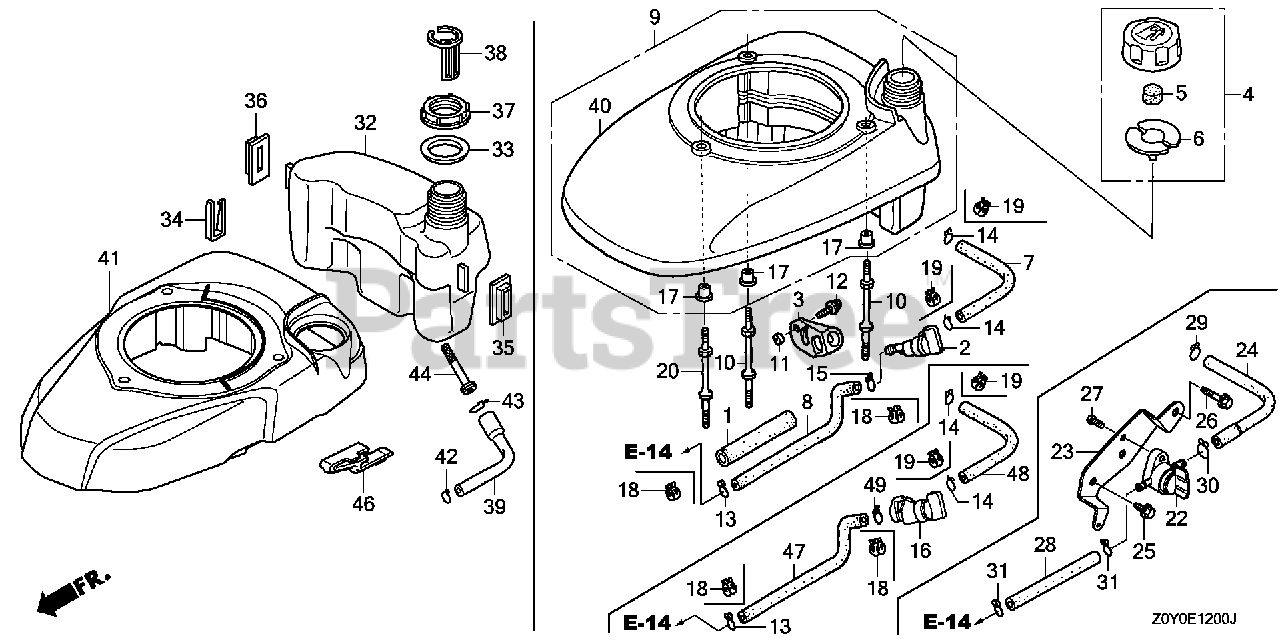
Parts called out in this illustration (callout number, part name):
1	RUBBER, SUPPORTER (107MM)
4	CAP ASSY., FUEL TANK
5	SPONGE, FUEL CAP BREATHER
6	GASKET, FUEL CAP
7	TUBE, FUEL (5.3X150) (FKM)
7	BULK HOSE, FUEL (5.5X3000) (Honda Code 5338587). (5.5X150)
8	TUBE, FUEL
8	TUBE, FUEL (FKM)
9	COVER, FAN *NH1* (BLACK)
9	COVER, FAN *R280* (POWER RED)
10	BOLT, STUD
11	COLLAR, FUEL PETCOCK
12	SCREW-WASHER (5X10)
13	CLIP, TUBE (B8)
14	CLIP, TUBE (B10)
15	CLIP, TUBE (B8)
16	PETCOCK ASSY.
17	COLLAR, FAN COVER (Honda Code 5580527). (N/A: SEE ASSEMBLY)
18	CLIP, TUBE (D8)
19	CLAMP, TUBE (D10)
20	BOLT, STUD
47	TUBE, FUEL
47	TUBE, FUEL (FKM)
48	TUBE, FUEL (5.3X150) (FKM)
48	BULK HOSE, FUEL (5.5X3000) (Honda Code 5338587). (5.5X150)
49	CLIP, TUBE (B8)
